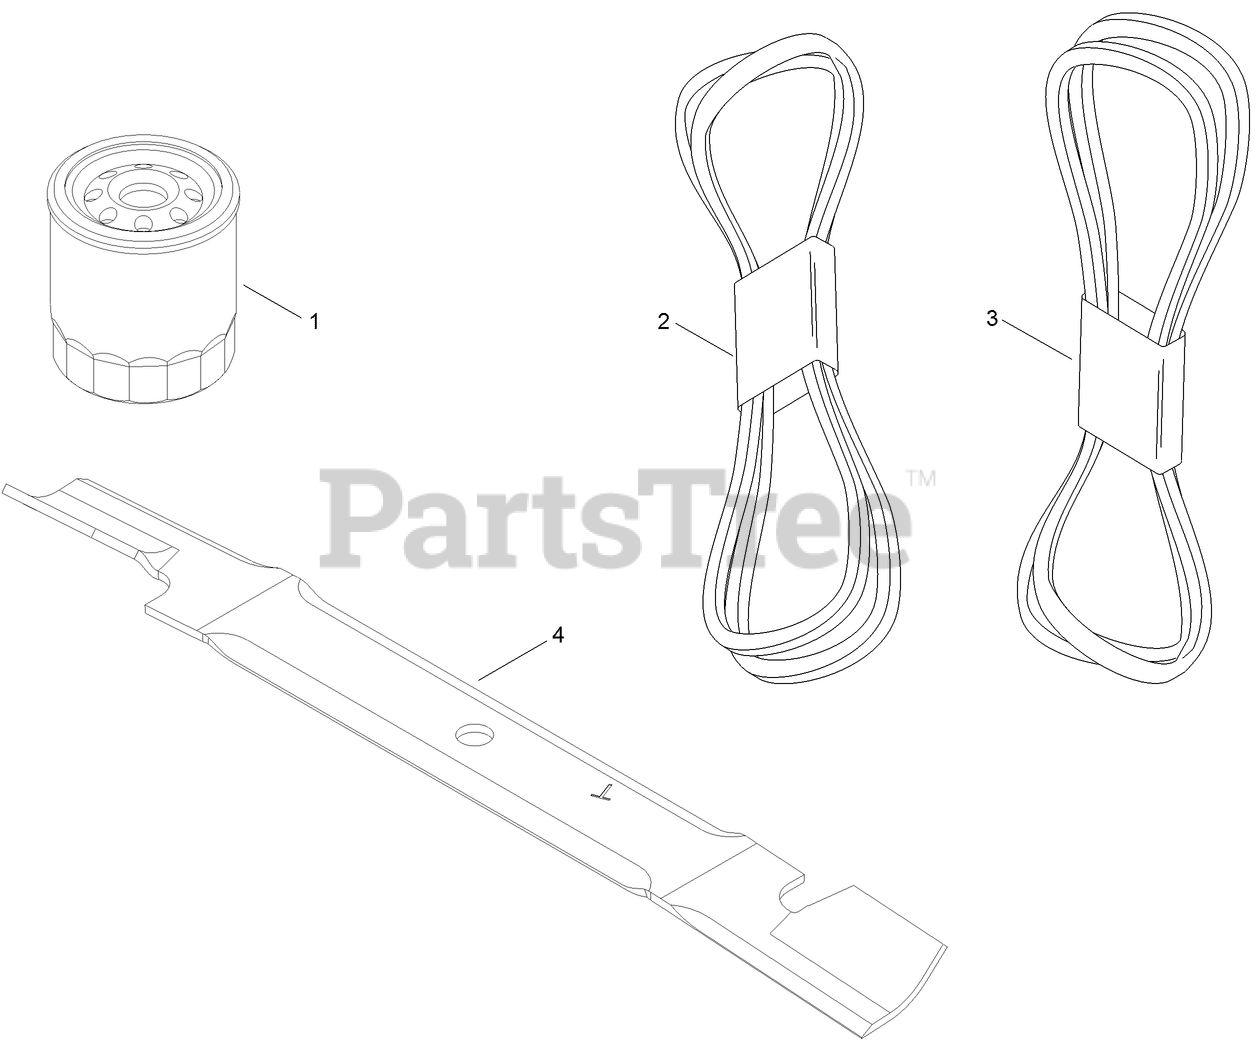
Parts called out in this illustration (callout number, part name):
1	ELEMENT-OIL FILTER, HYD
2	V-BELT
3	BELT-V
4	BLADE-HI FLOW, 20.5 INCH
